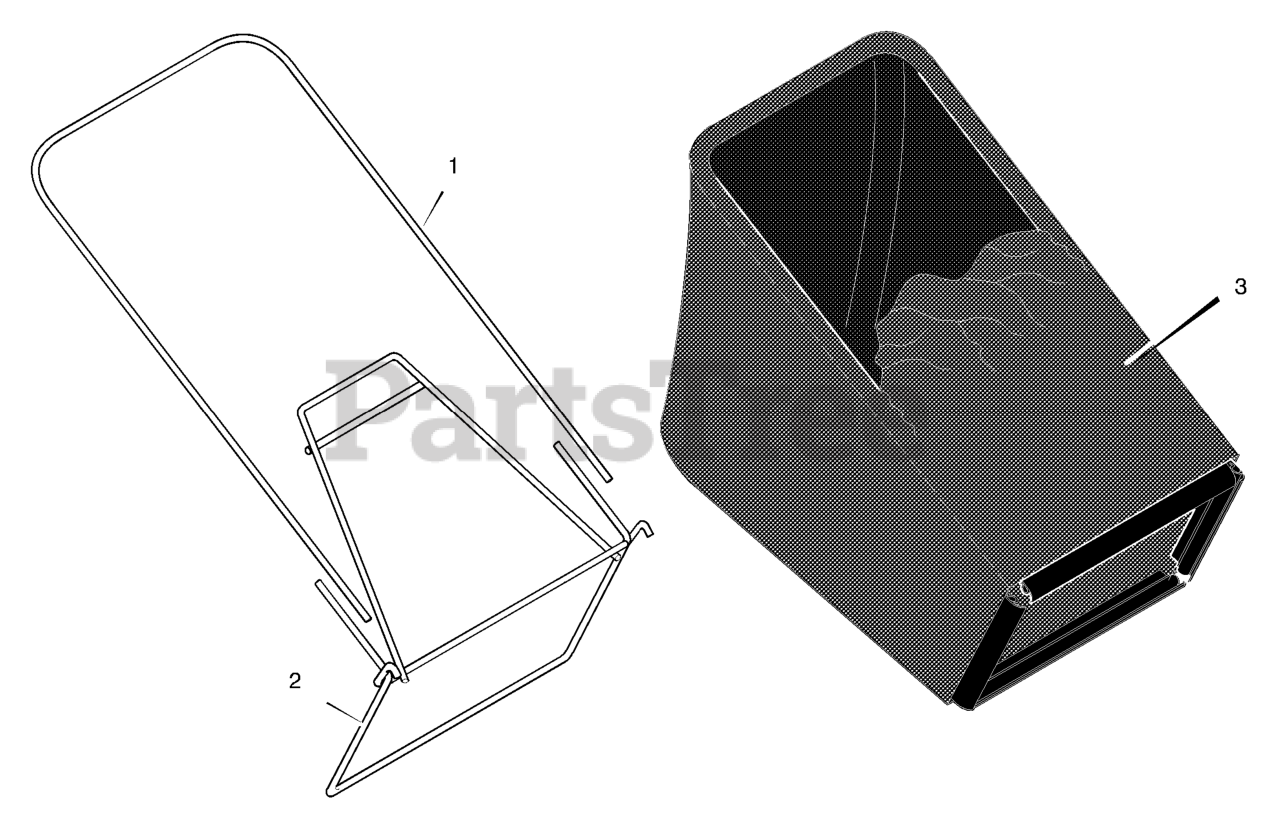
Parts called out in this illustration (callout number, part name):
1	Tube, Bag
1-3	Assembly, Bag
2	Frame Assembly
3	Bag, Cloth - Gray
